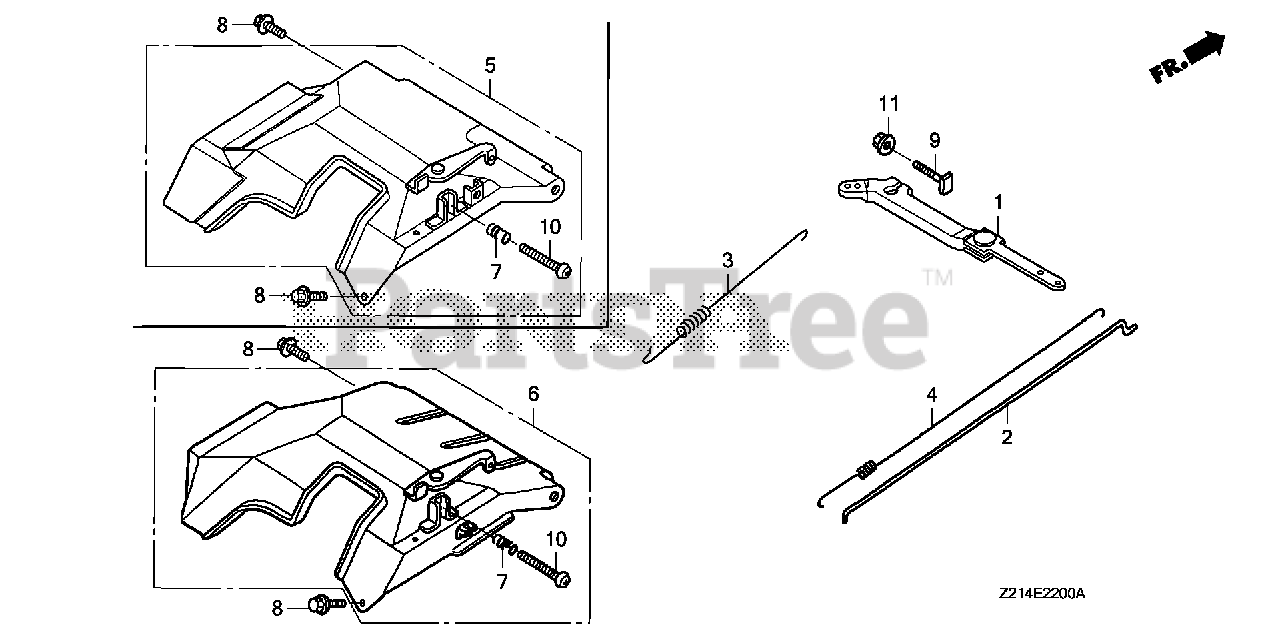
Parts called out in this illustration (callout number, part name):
1	ARM, GOVERNOR
2	ROD, GOVERNOR
3	SPRING, GOVERNOR (L=145.0MM) (WIRE DIAMETER 1.0MM)
4	SPRING, THROTTLE RETURN
5	CONTROL ASSY.
7	SPRING, CONTROL ADJUSTING
8	BOLT, FLANGE (6X12) (CT200)
9	BOLT, GOVERNOR ARM
10	SCREW, PAN (5X35)
11	NUT, FLANGE (6MM)
